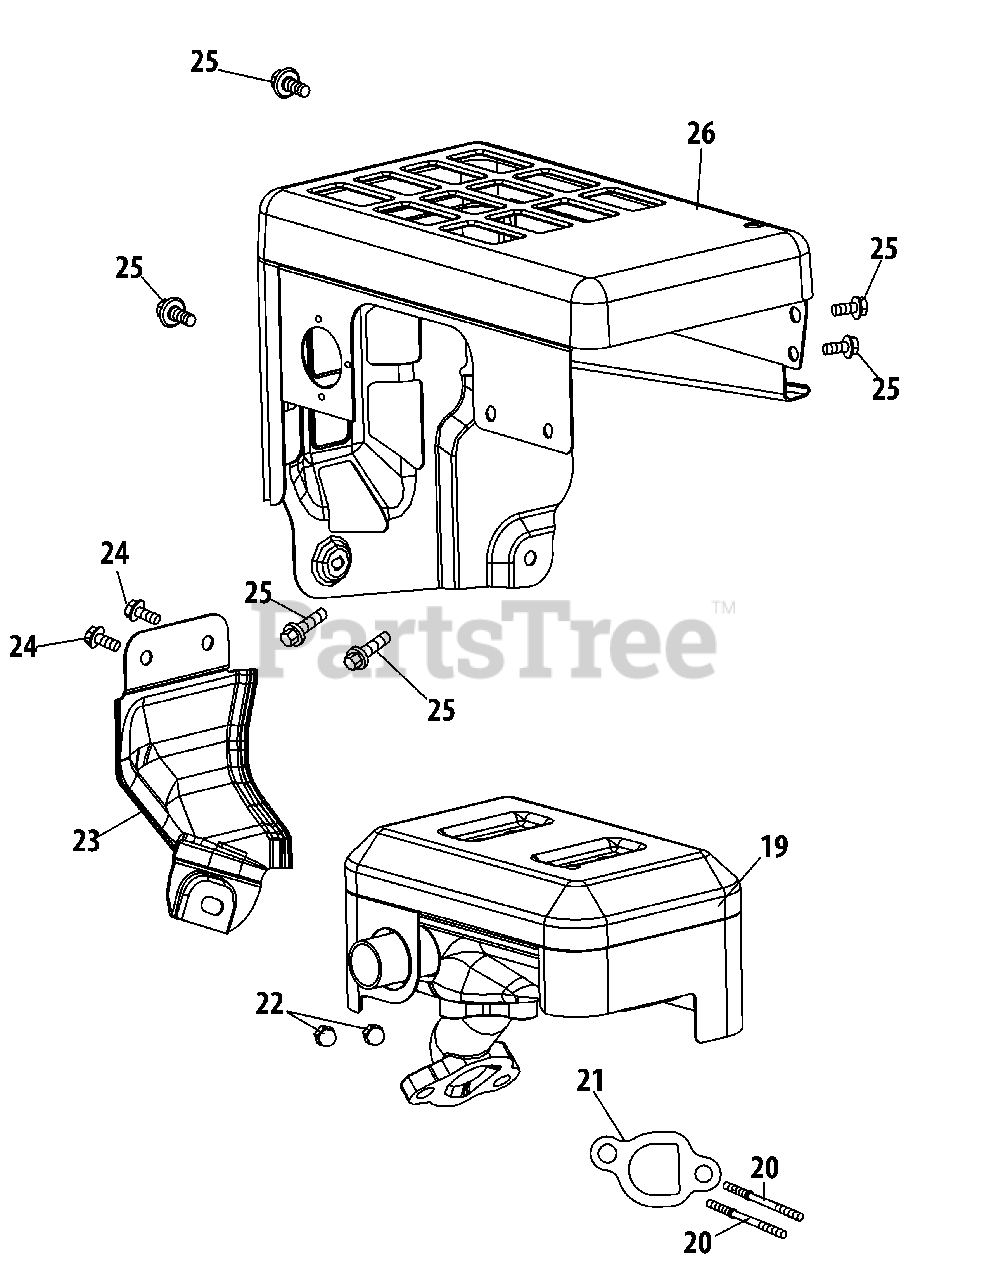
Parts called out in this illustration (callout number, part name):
19	Muffler Assembly
20	Muffler Stud M8×36
20	Muffler Stud Assembly
21	Exhaust Pipe Gasket
22	Nut, M8
23	Exhaust Pipe Shield
24	Bolt M6×10
25	Bolt M6×12
26	Muffler Shield
